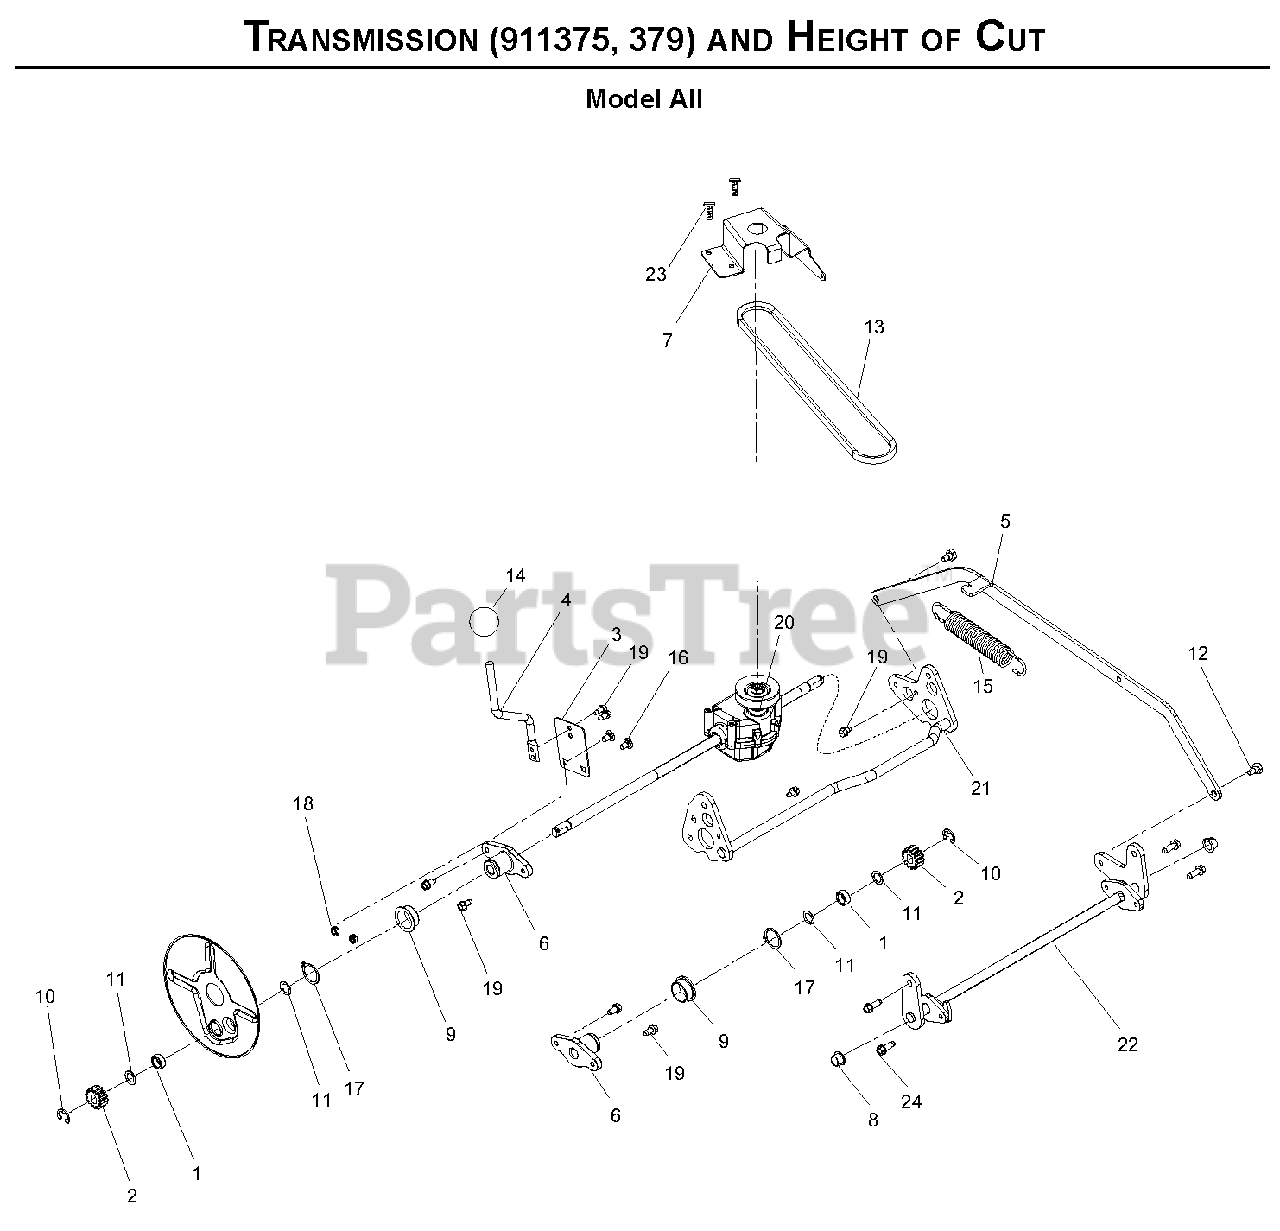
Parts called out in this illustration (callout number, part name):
1	BSHG, SPCR.500X.750X.321 PM
2	GEAR, PINION, LM WHEEL DRIVE
3	PLATE, HOC SPRING
4	LEVER, HOC ADJUSTMENT
5	LINK, HOC CONNECT
6	HUB, LM REAR AXLE
7	BRKT, BELT GUIDE
8	BUSHING, POLYLINER-.50 SPLIT
9	BSHG-FLG 1.0X1.125X.50X1.375 R
10	RG-RTNG-EXT .500X.042 (E)
11	WASHER, .500X.750X.020 THRUST
12	BOLT, SHLDR .320X.210X.25-20
13	V-BELT, 3L-WRAPPED
14	KNOB,BALL -BLACK 1.47" .375-16
15	SG-TENS .121X1.00X6.5 WLD 12
16	@BLT-RDHDSQNK .25-20X.50 G5YZ
17	RG-RTNG-EXT 1.00X.042
18	NUT-LK-CTR JAM .25-20 YWZC
19	SCR-TAP .25-20X.50 HWH TR YWZ
20	TRANSAXLE, AUTOMATIC, LM, 9:1
21	WMT,RR AXL(SEE BULLETIN B2119)
22	WMT, LM FRONT AXLE
23	SCR-TAP 10-14X.75PLSTITE BLKOX
24	SCR-TAP-PM .25-20X.75 TR YWZ
